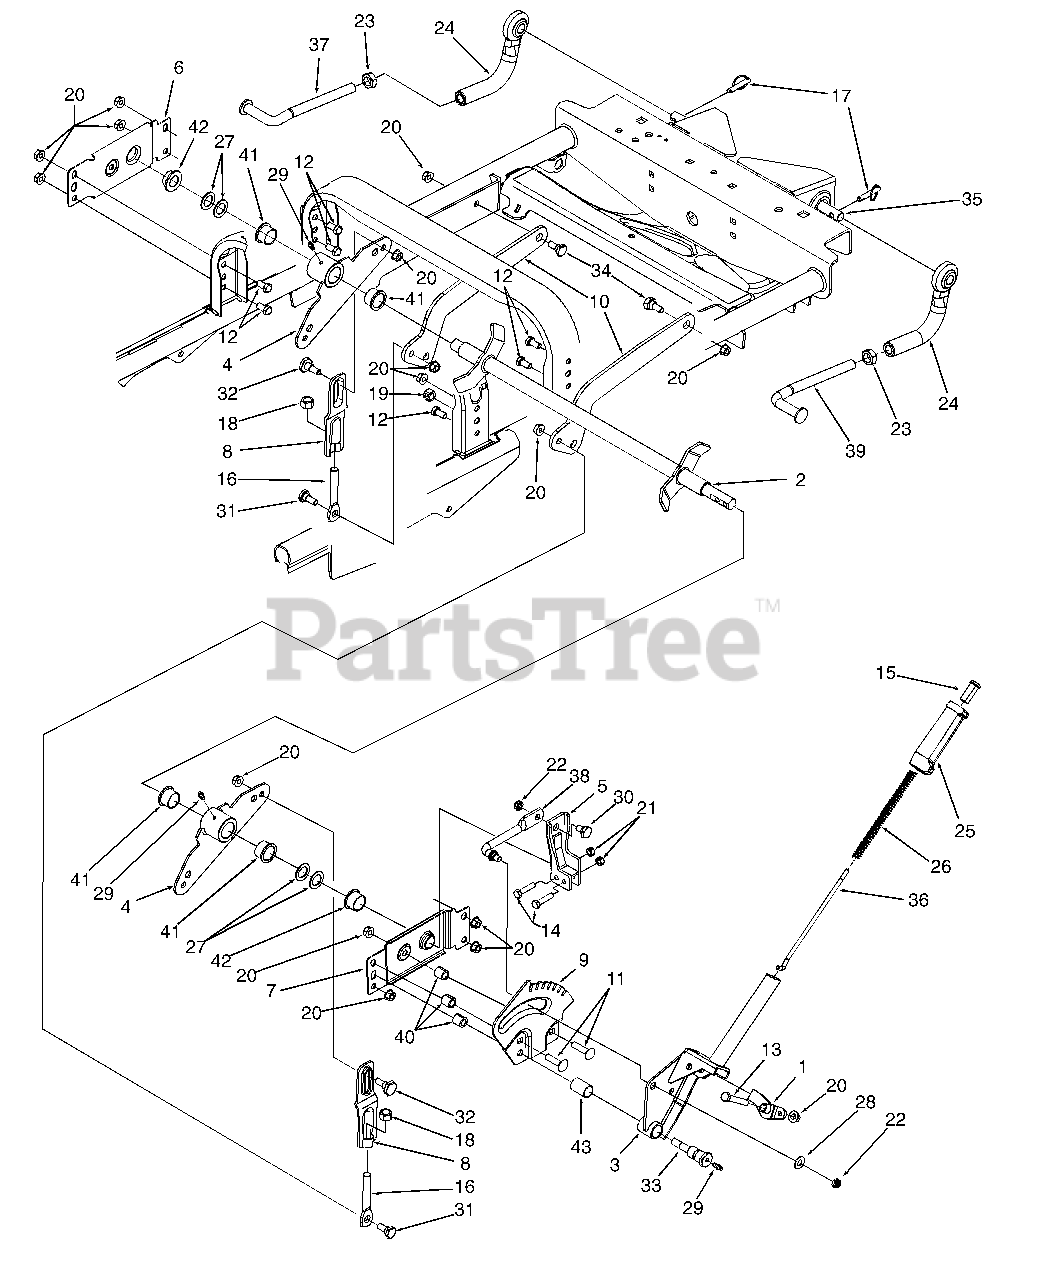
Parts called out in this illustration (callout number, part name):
6	Bracket, Shaft Mtg. LH
7	Bracket, Shaft Mtg. RH
10	Link, Parallel Lift
11	Bolt, Carriage, 3/8-16 x 1.5
12	Screw, Hex Cap, 3/8-16 x .75 GR5
13	Screw, Hex Cap, 3/8-16 x 2-1/4
14	Screw, Hex Cap, 5/16-18 x 1.38 GR5
15	Button, Handle
16	Link, Eye Bolt Adjustment
17	Clevis Pin, w/ Detent Ball
18	Nut, Hex, 1/2-13
19	Nut, Hex Center Lock, 7/16-14
20	Nut, Hex Flange Lock, 3/8-16
21	Nut, Hex Center Lock, 5/16-18
22	Nut, Hex Insert Lock Jam 3/8-16
23	Nut, Hex Jam, 5/8-18
24	Link, Parallel
25	Grip, Deck Lift Handle
26	Spring, Compression
27	Washer, Flat, .79 x 1.24 x .06
28	Washer, Flat, .406 x .875 x .06
29	Fitting, Grease
30	Bolt, Shoulder
31	Bolt, Shoulder
32	Bolt, Shoulder
33	Bolt, Lift Handle Shoulder
34	Bolt, Shoulder
35	Rod, Parallel Link Front Mtg.
36	Rod, Lift Handle
37	Rod, Connecting LH
38	Rod, Lift Link
39	Rod, Connecting RH
40	Spacer, .448 x .688 x .673
41	Bearing, Flange, 1.0 ID
42	Bearing, Flange, .75 ID x 1.0 OD
43	Bearing, Sleeve, .75 x .875 x 1.25
